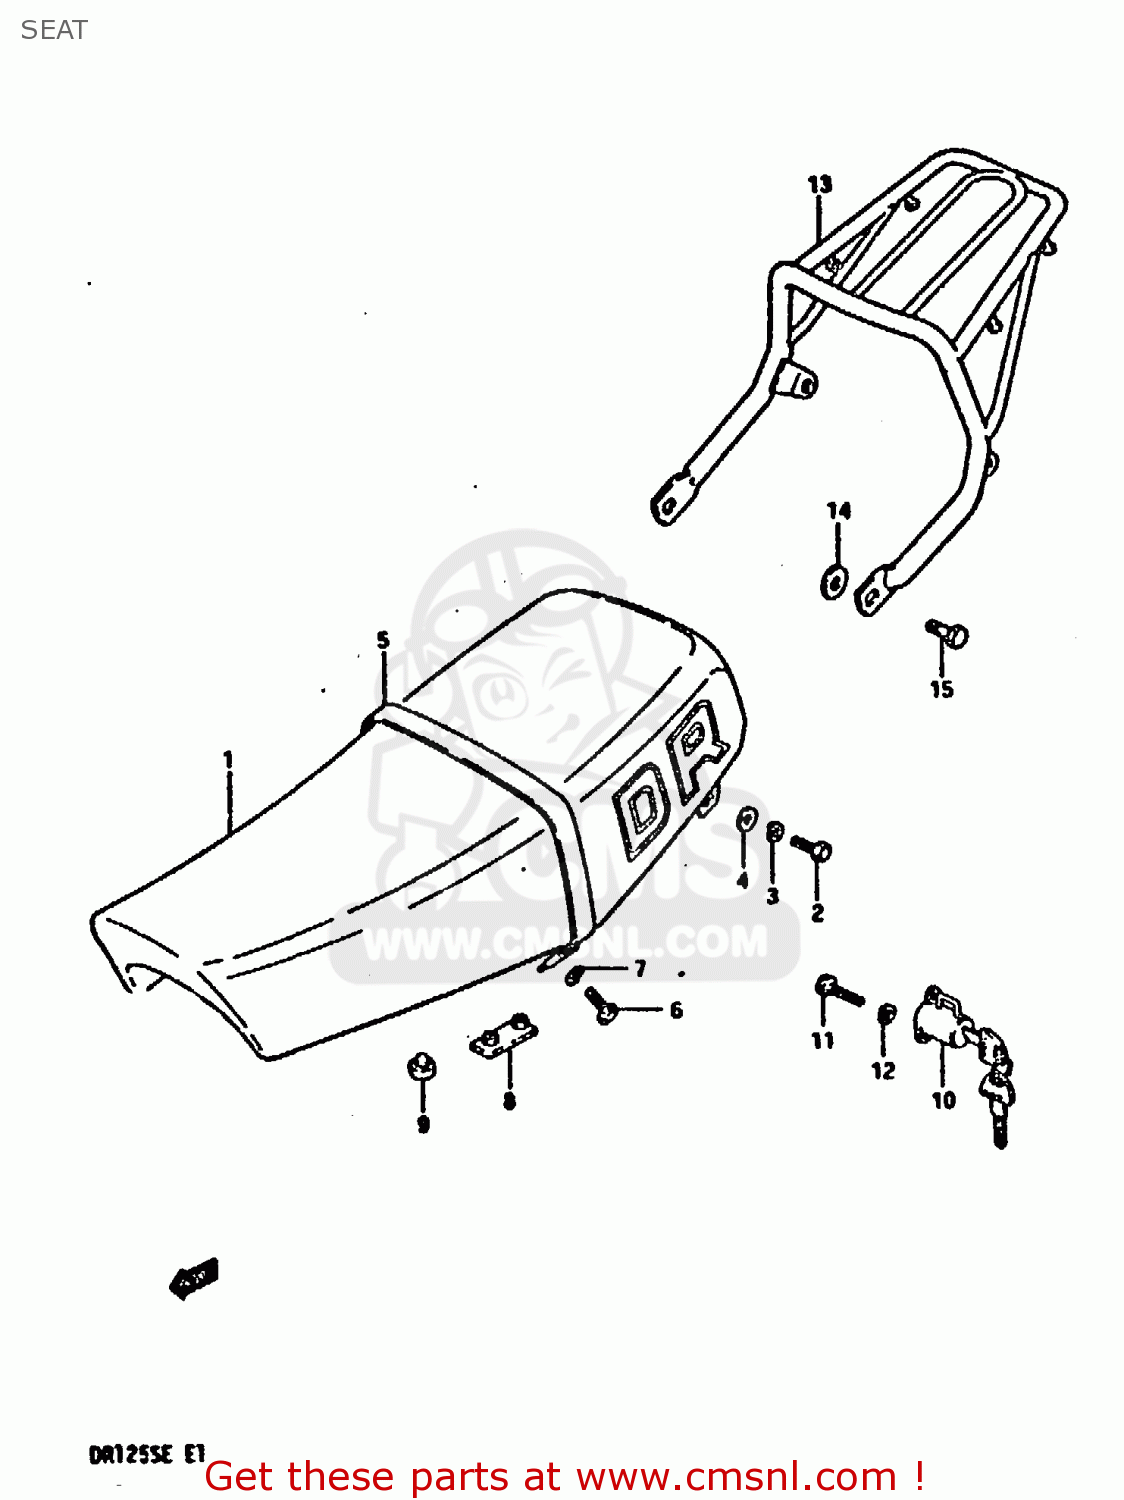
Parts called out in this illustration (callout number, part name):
1	SEAT ASSY (BLUE)
2	BOLT
3	LOCK WASHER
4	WASHER,8.5X16X
5	BAND,SEAT
6	BOLT
7	LOCK WASHER
8	CUSHION
9	CUSHION
10	LOCK ASSEMBLY,HELMET
11	BOLT 6X11
12	LOCK WASHER
13	CARRIER
14	WASHER (8.5X24X2.3)
15	BOLT
